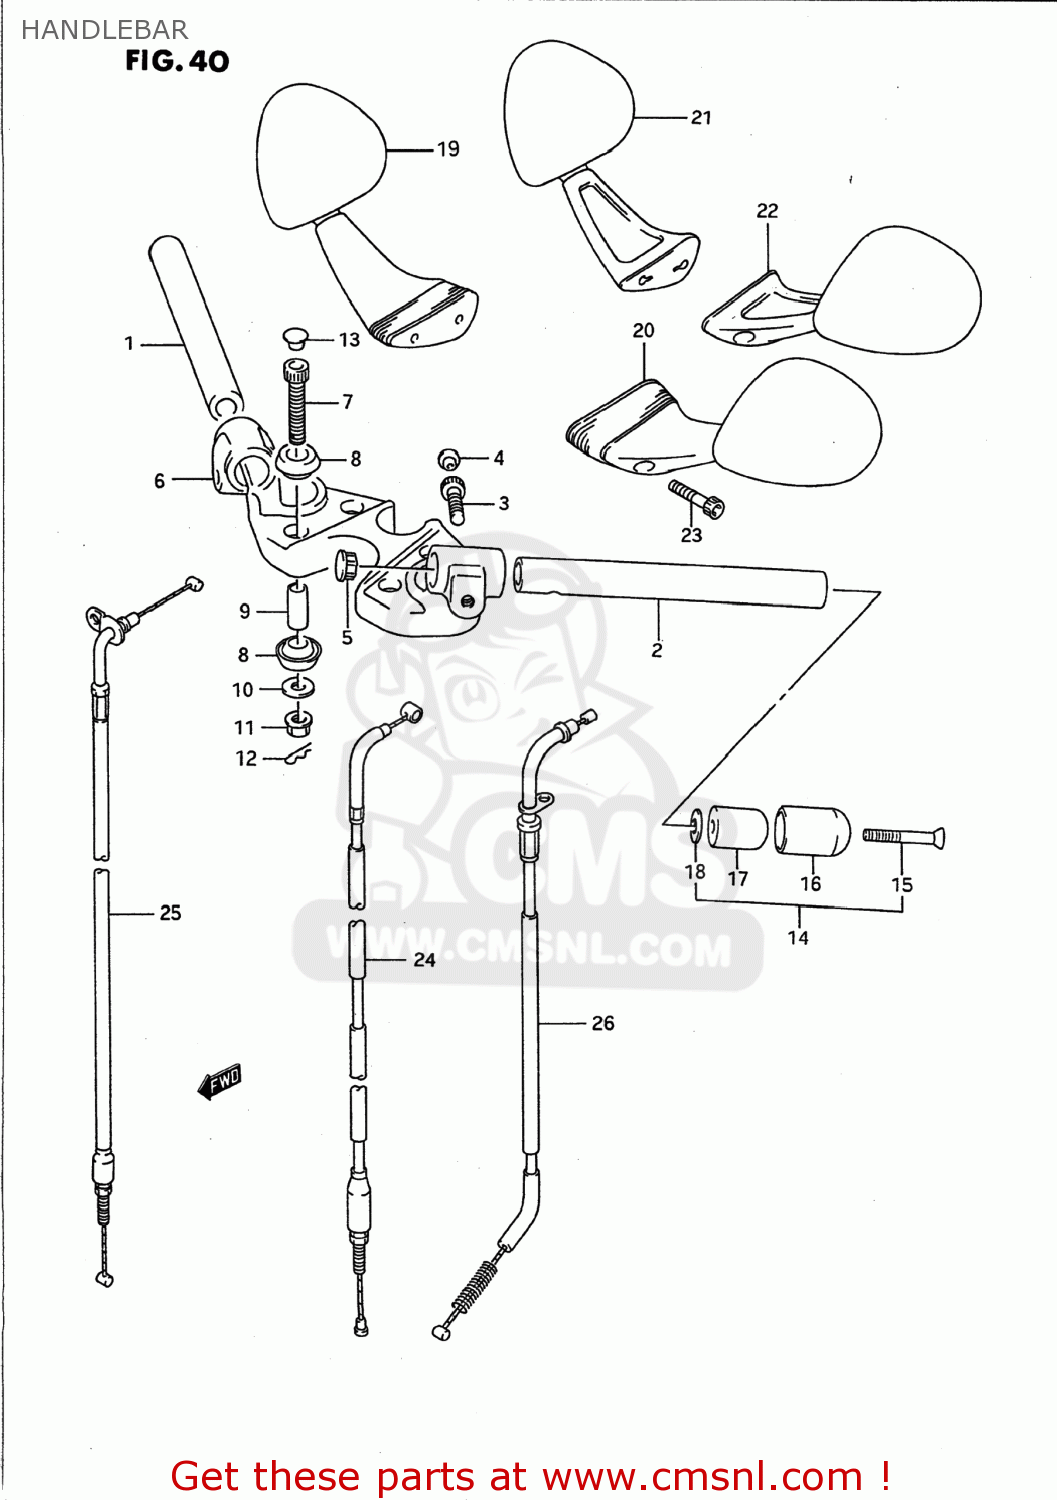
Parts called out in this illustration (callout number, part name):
1	HANDLEBAR,R
2	HANDLEBAR,L
3	BOLT
4	CAP(OD:14.5)
5	CAP,HANDLEBAR
6	HOLDER,HANDLEBAR
7	BOLT(10X77)
8	RUBBER,HANDLE HOLDER
9	SPACER,HANDLEBAR BRACKET
10	WASHER
11	NUT 10MM
12	CLIP
13	CAP(OD:11)
14	BALANCER SET,HANDLEBAR
15	SCREW
16	CAP,HANDLE BALANCER
17	BALANCER,HANDLEBAR
18	SPACER,BALANCER
19	MIRROR ASSEMBLY,REAR VIEW
20	MIRROR ASSEMBLY,REAR VIEW
21	MIRROR ASSEMBLY,REAR VIEW
22	MIRROR ASSEMBLY,REAR VIEW
23	BOLT
24	CABLE ASSY,CLUTCH
25	CABLE ASSY,THROTTLE
26	CABLE,STARTER
